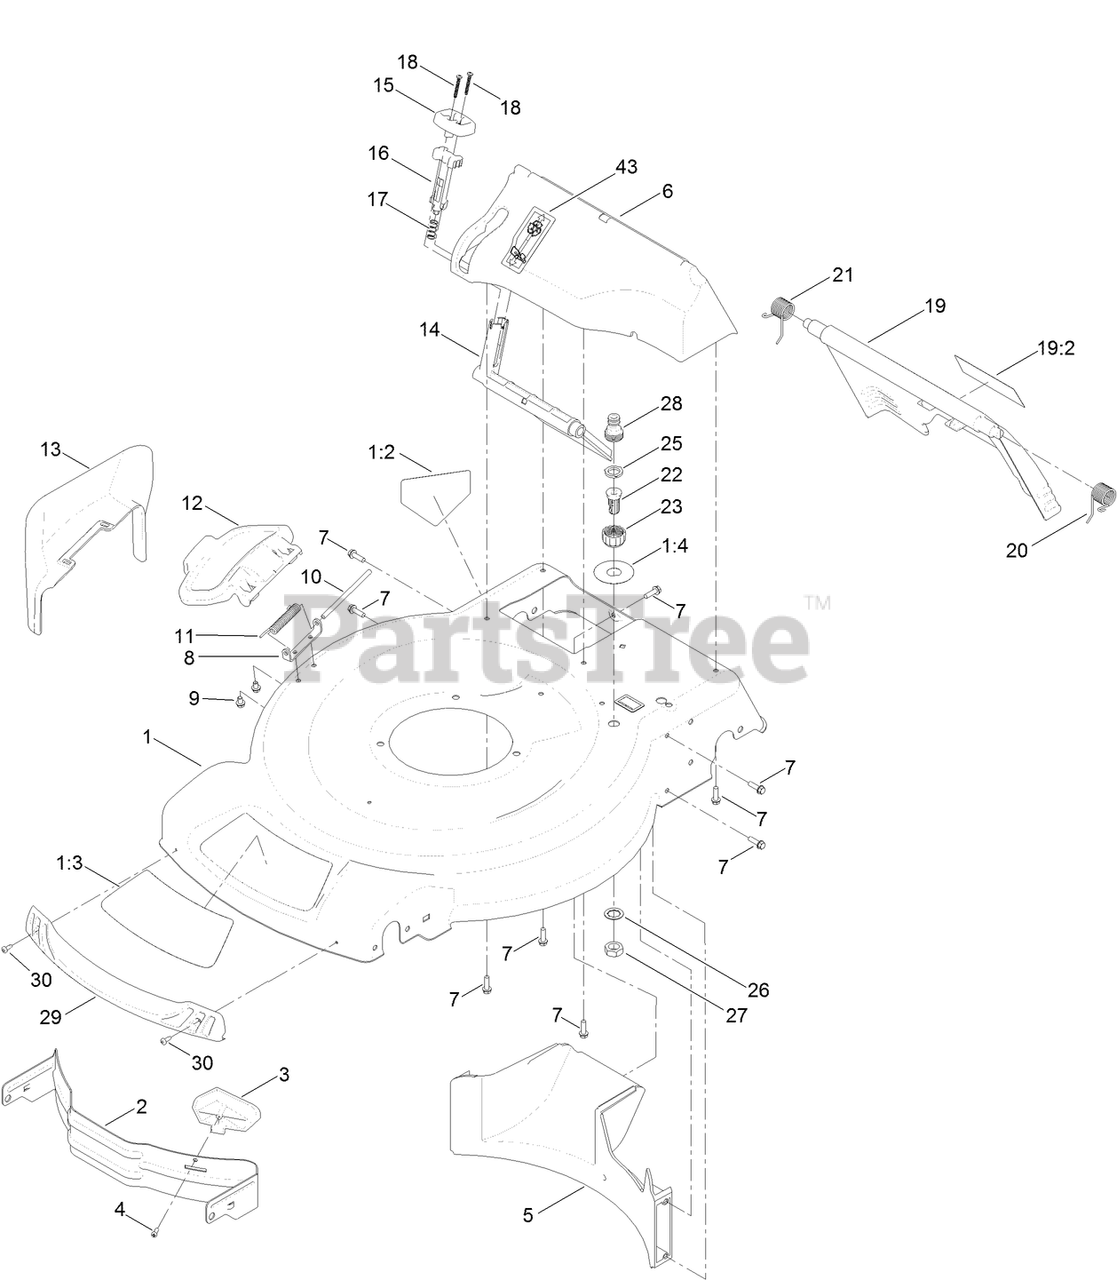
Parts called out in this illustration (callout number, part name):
1	HOUSING ASM
1:2	DECAL-DANGER
1:4	DECAL-PORT, WASHOUT
2	BAFFLE-FRONT
3	KICKER-FRONT
4	SCREW-PPH
5	BAFFLE-REAR
6	CHUTE-RECYCLE
7	SCREW-HWH
8	BRACKET-COVER
9	SCREW-HWH
11	SPRING-TORSION
12	DEFLECTOR-SIDE
13	CHUTE-DISCHARGE, SIDE
14	DEFLECTOR-RECYCLE
15	KNOB-RECYCLE
16	LATCH-RECYCLE
17	SPRING-COMPRESSION
18	SCREW-PPH
19:2	DECAL-WARNING
20	SPRING-TORSION
21	SPRING-TORSION
22	PORT-WASHOUT
23	COUPLING-HOSE, WASHOUT PORT
25	WASHER-SEAL, WASHOUT PORT
26	WASHER-LOCK
27	NUT-JAM
28	ADAPTER-CONNECT, QUICK
29	BUMPER
30	SCREW-FORMING, THREAD
